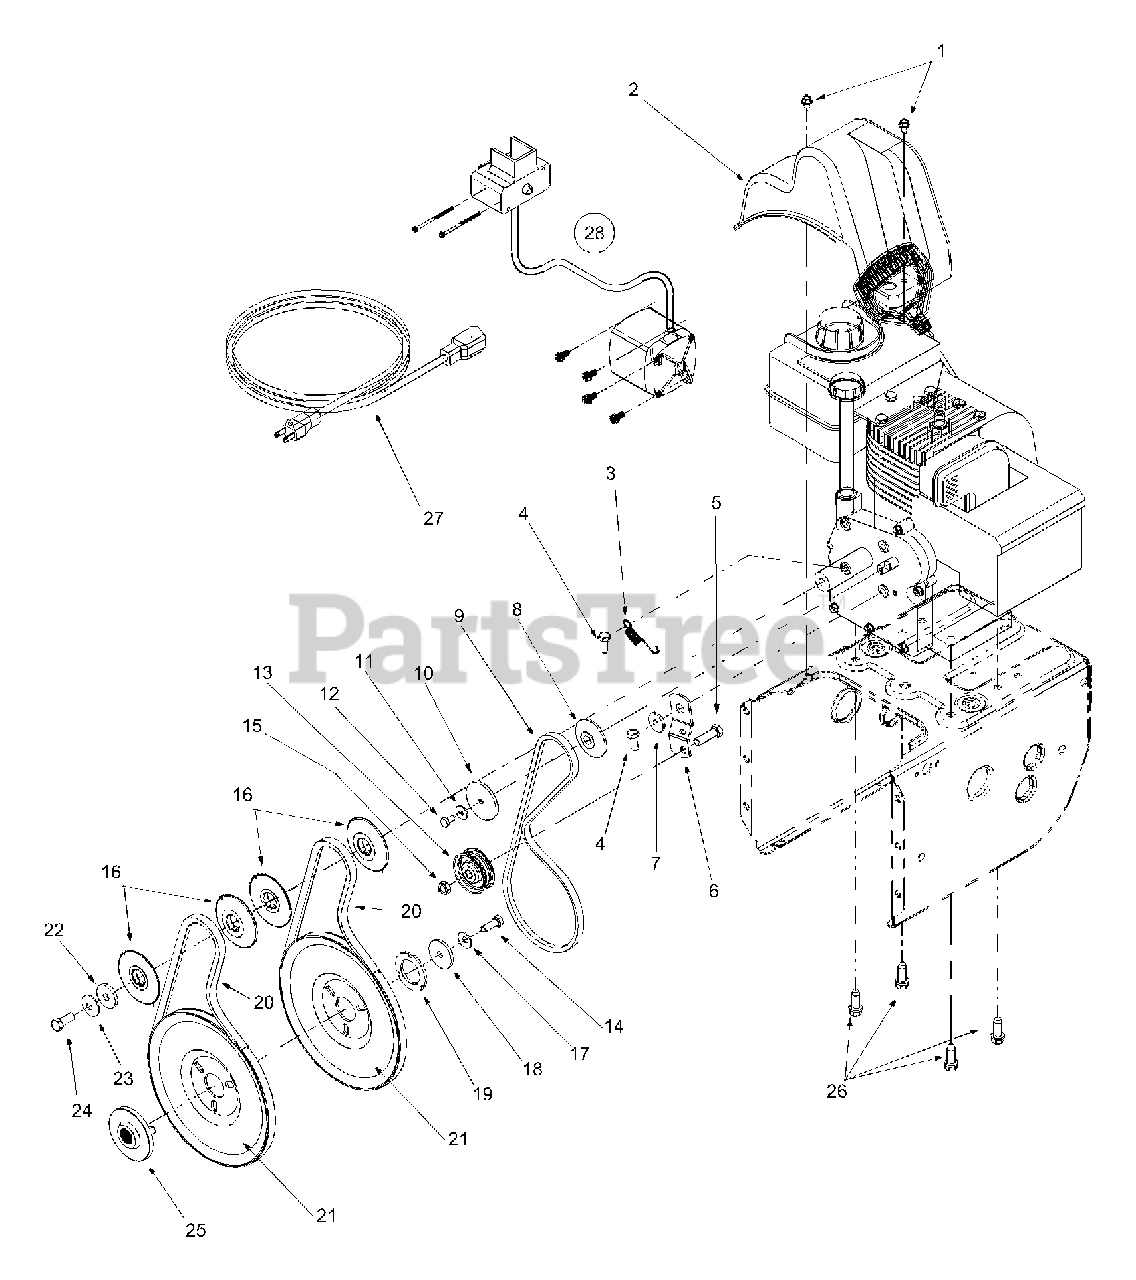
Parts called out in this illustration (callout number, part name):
1	Hex Washer Screw 1/4-20 x.625
2	Belt Cover
3	Extension Spring
4	Hex Screw 5/16-24 x .75
5	Hex Cap Screw 3/8-16 x 1.25
8	Pulley Half
9	V-Belt
10	Pulley Half
11	Bell Washer
12	Hex Cap Screw 1/4-28 x .50
13	Flat Idler
14	Lock Cap Screw 5/16-24 x .875
15	Lock Jam Nut 3/8-16
16	Pulley Half
17	Bell Washer
18	Flat Washer
19	Washer
20	Belt
21	Auger Pulley
22	Flat Washer
23	Bell Washer
24	Hex Cap Screw 3/8-24
25	Pulley
26	Hex Washer Screw 3/8-16 x 1.0
27	Extension Cord
28	Electric Start Kit
